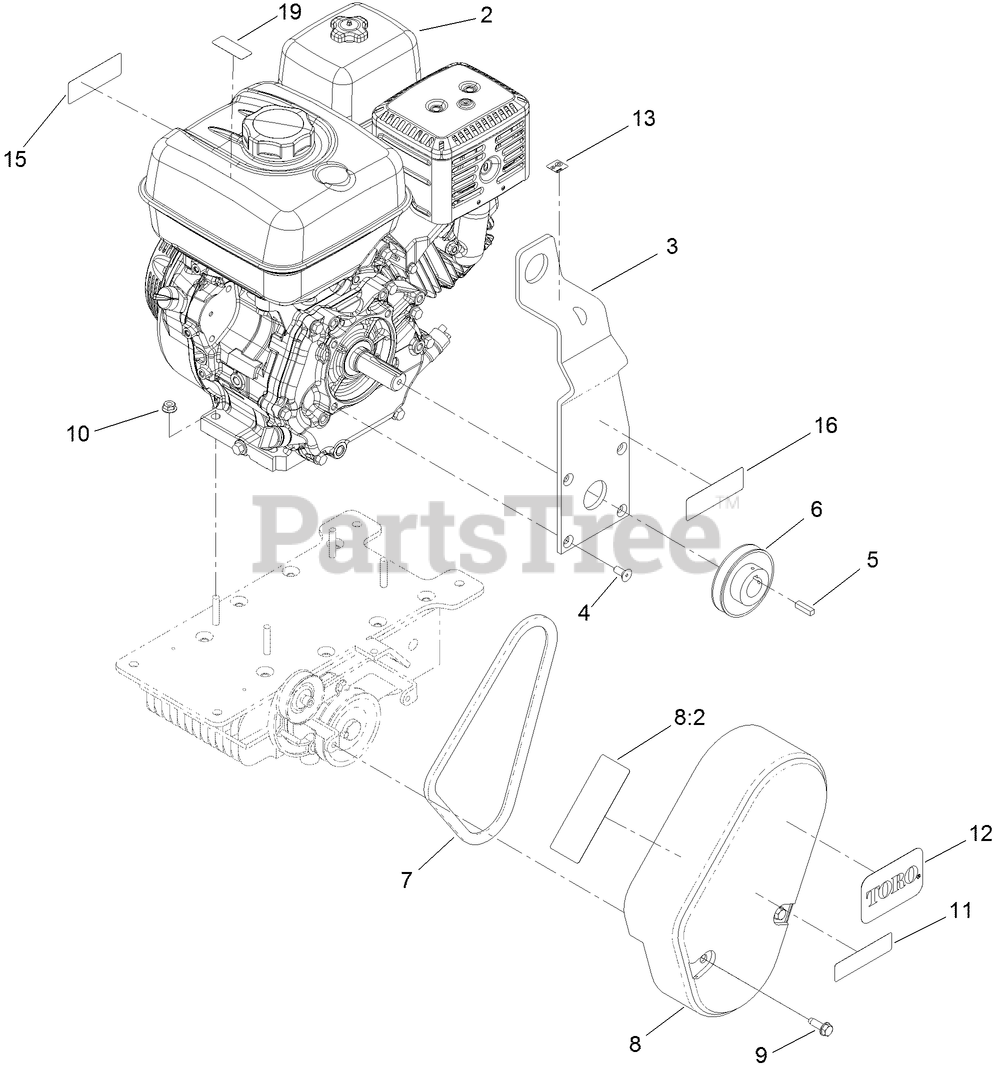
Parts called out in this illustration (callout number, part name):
2	ENGINE-HONDA, GX240
3	PLATE-EYE, LIFT
4	SCREW
5	KEY-SQUARE
6	SHEAVE
7	BELT-V
8	BELT GUARD ASM
8:2	DECAL-WARNING
9	SCREW-THD ROLL, HWH
10	NUT-FLANGE
13	DECAL-POINT, LIFT
15	DECAL-ARRESTER, SPARK
16	DECAL-WARNING
19	DECAL-WARNING, ETHANOL
